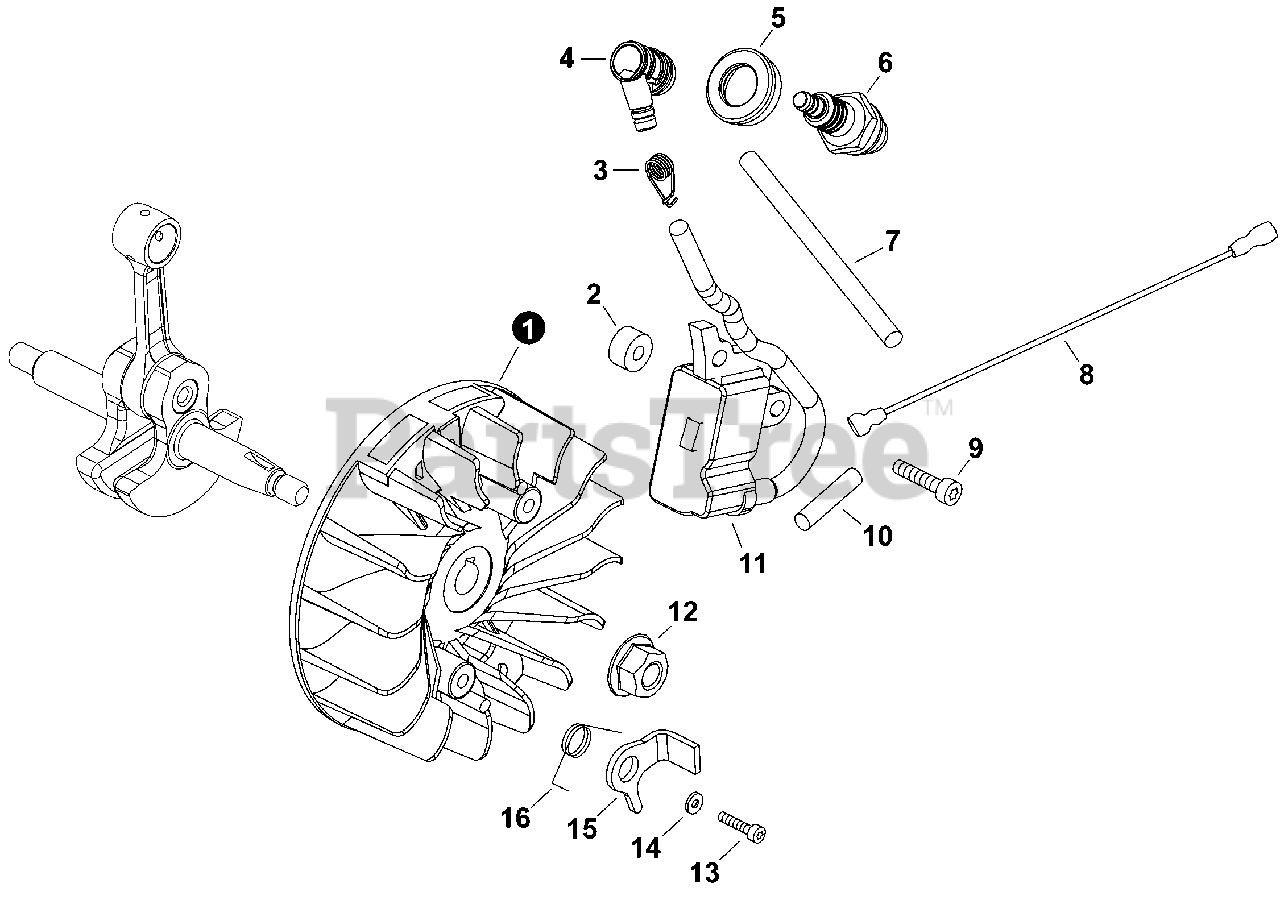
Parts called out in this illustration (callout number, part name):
1	FLYWHEEL
2	COLLAR 5
3	TERMINAL, SPARK PLUG
4	CAP, SPARK PLUG
5	SEAL, SPARK PLUG
6	SPARK PLUG - BPMR8Y
7	TUBE, INSULATOR
8	LEAD - IGNITION
9	BOLT, TORX 5x16
10	TUBE, INSULATOR
11	COIL, IGNITION
12	NUT, FLANGE M8x1.25
13	BOLT, TORX 5x12
14	SPACER 5.2x8x2.1
16	SPRING, TORSION
